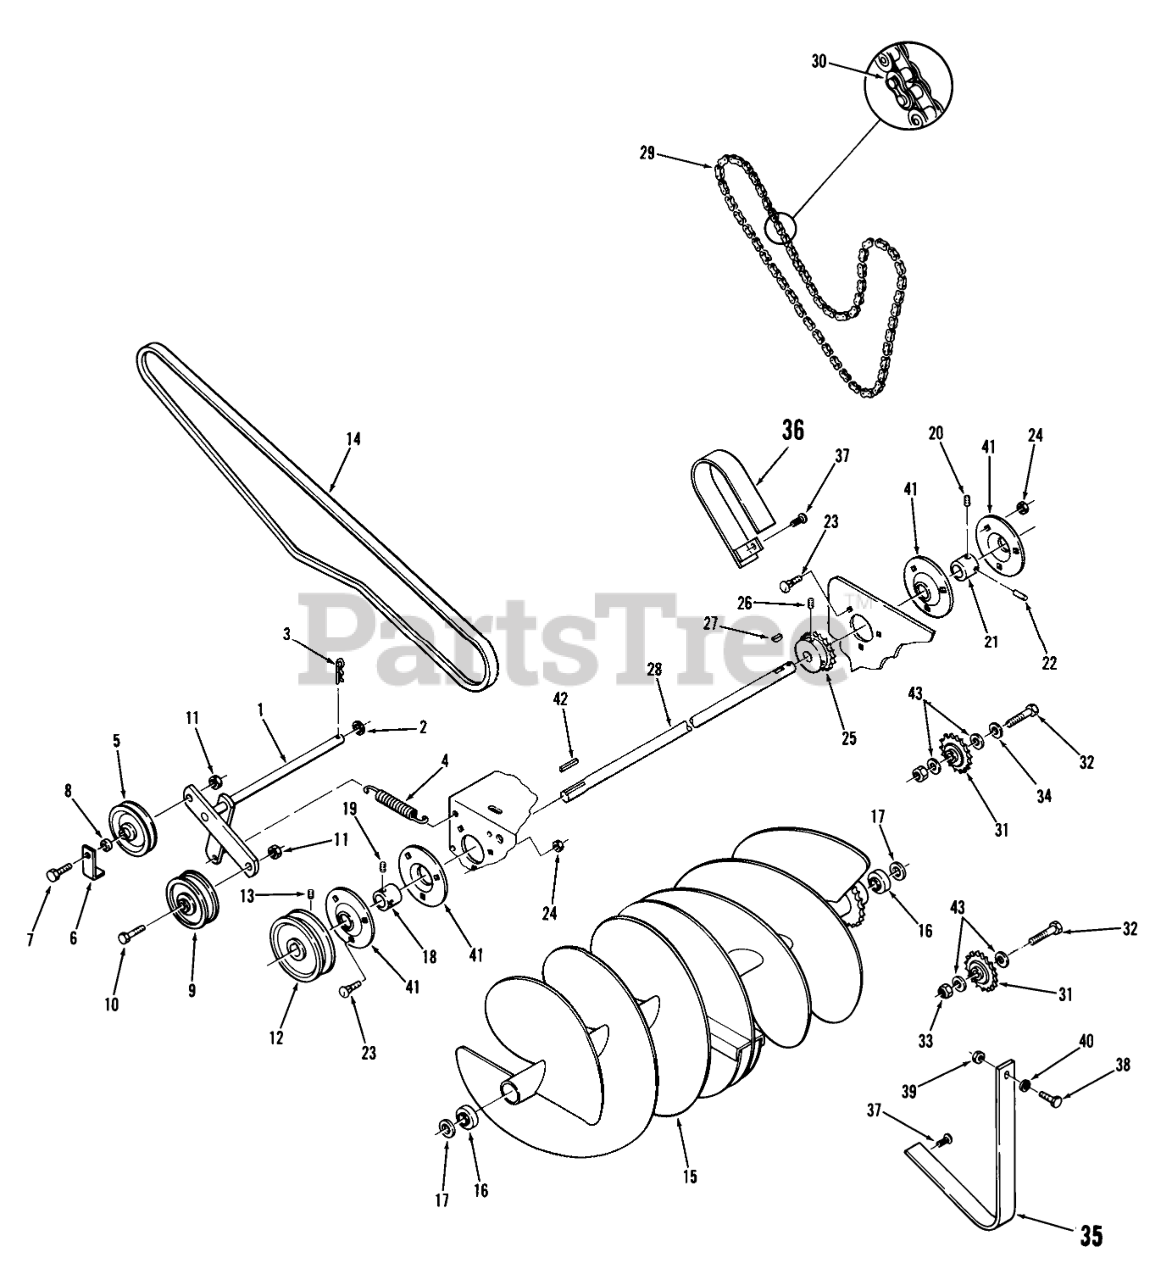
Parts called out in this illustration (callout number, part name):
1	ASSY IDLER ARM R
2	Washer
3	Hairpin
4	SPRING R
5	PULLEY-IDLER
6	Spacer
7	Bolt
8	SPACER
9	Idler Pulley
10	BOLT
11	NUT
12	Pulley
13	Set Screw
14	V-BELT
15	Auger
16	BEARING-BALL
17	Washer
18	Ball Bearing
19	Set Screw
20	SET SCREW
21	Ball Bearing
22	PIN-ROLL, SPIROL
23	Bolt
24	Nut
25	SPROCKET
26	SCREW-SET
27	Key
28	SHAFT
29	CHAIN
30	MASTER LINK CHAIN
31	Idler Sprocket
32	H H C S
33	Eslok Nut
34	SPACER
35	Guard-Inner
36	Guard-Outer
37	SCREW
38	H H C S
39	Nut 1/4-20
40	WASHER
41	FLANGE
42	KEY-STRAIGHT
43	Washer
